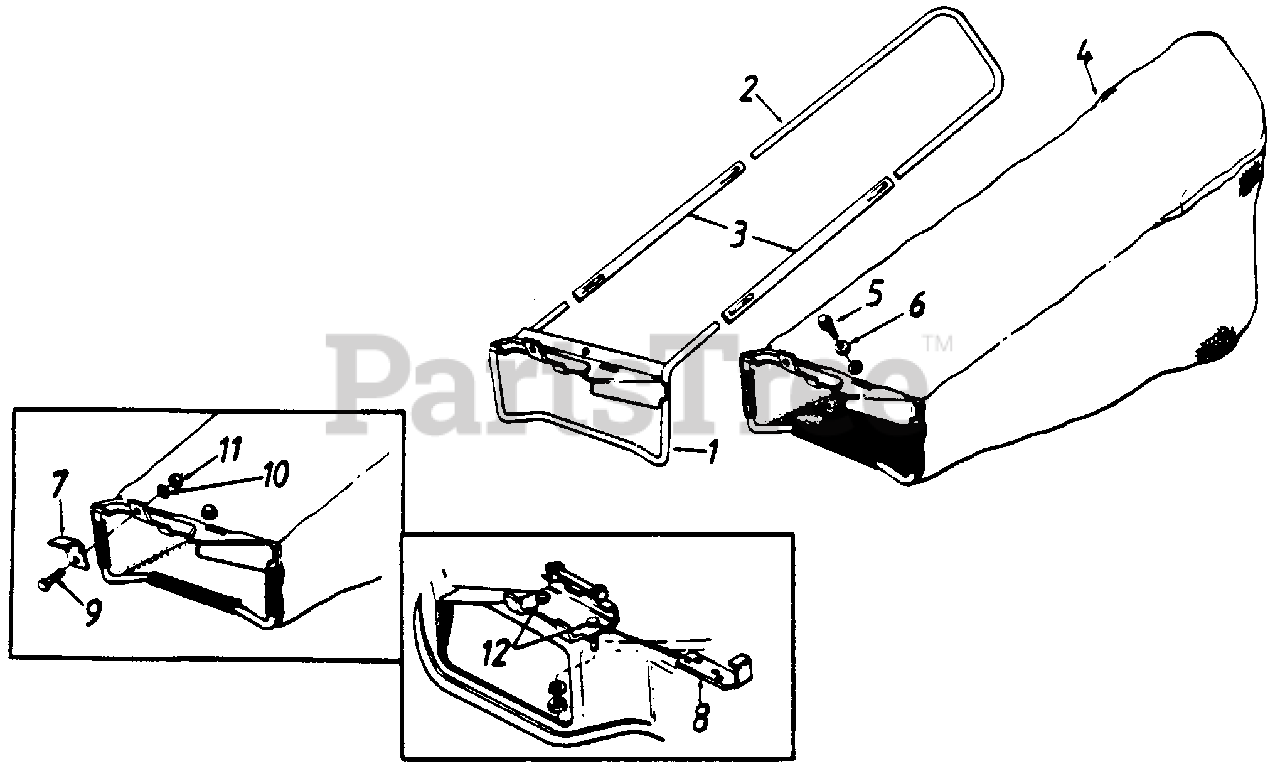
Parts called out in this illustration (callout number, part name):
4	Grass Bag
5	Hex Wash Hd. TT-Tap Scr. 1/4-20 x 5 Lg.
6	Bell-Wash. 1/4" I.D.
7	Deflector Stop
8	Support Plate
9	Hex Bolt 1/4-20 x .5 Lg.
10	L-Wash. 1/4" I.D.
11	Hex Nut 1/4-20 Thd.
12	Hex Bolt l/4-20 x .s2 Lg.
